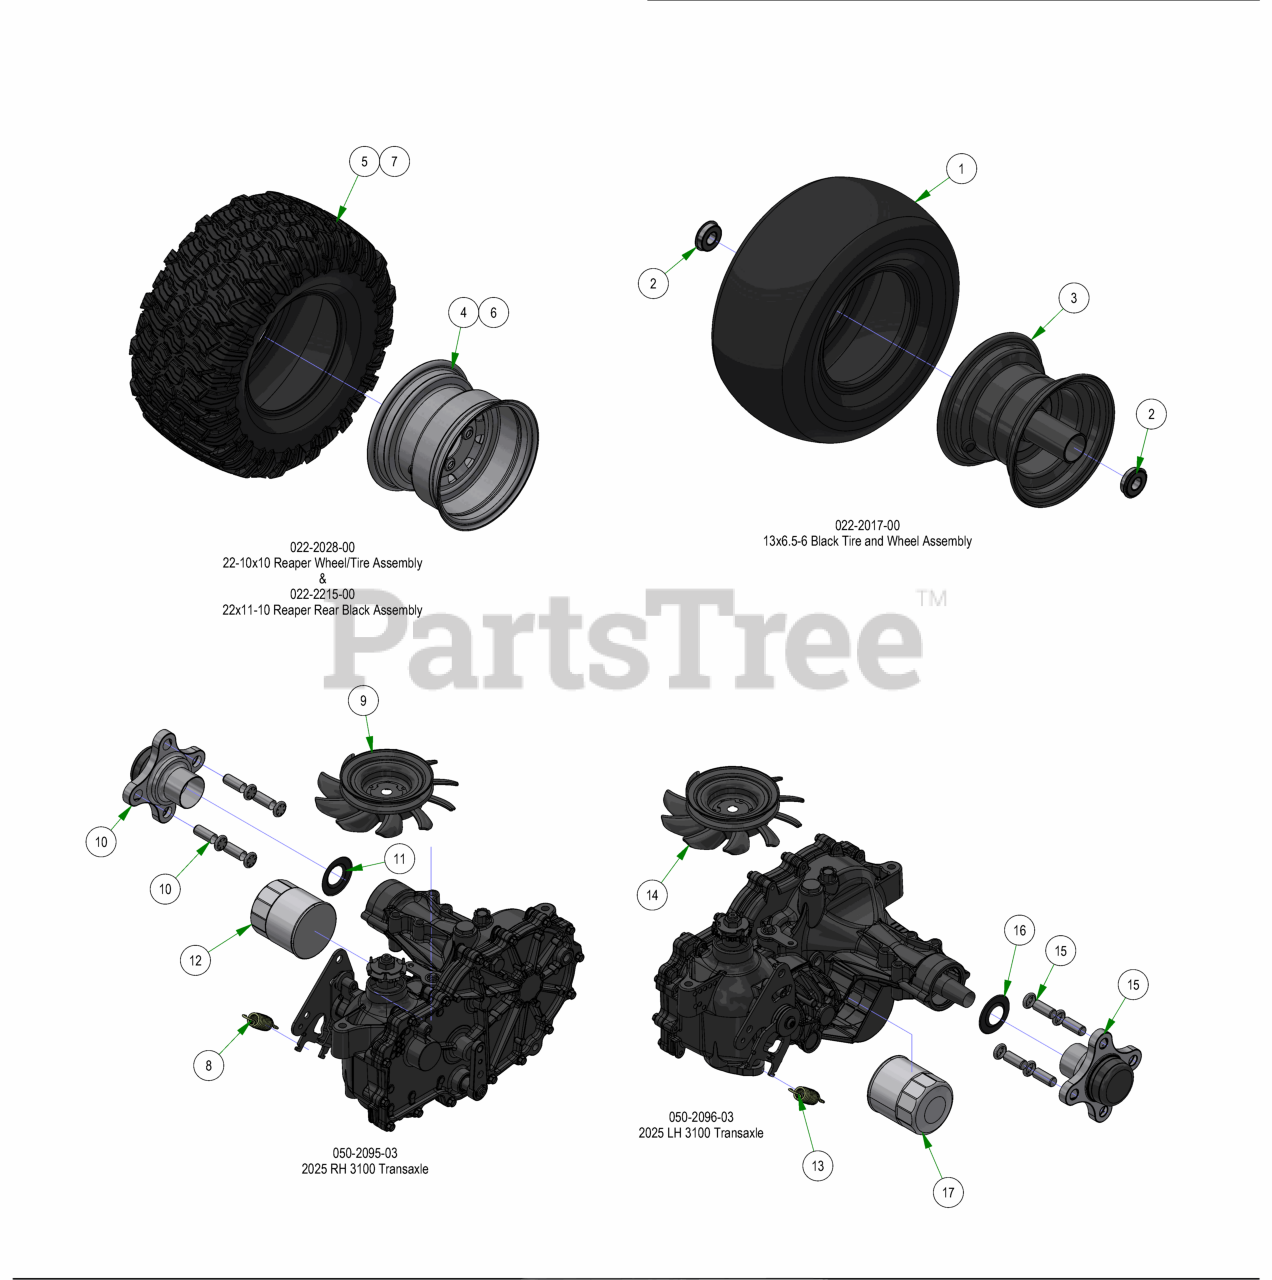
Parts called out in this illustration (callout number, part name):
1	13 x 6.50 - 6 Tire
2	Ball Bearing w/Retainer, 99502H-NR, .625 Bore x 1.375 OD x .4375 Width
3	Front Tire Rim
4	WHEEL, 10", BLACK
5	22-10x10 Reaper Tire Only
6	ZT Wheel Only 22x11-10
7	22x11-10 Reaper Rear TIRE ONLY
8	Transaxle Spring
9	2021 ZT/Maverick Transaxle Fan/Pulley Kit
10	ZT Transaxle Wheel Hub
11	2021 ZT/Maverick Transaxle Seat Kit (ZT-2800)
12	ZT Hydraulic Filter
13	Transaxle Spring
14	2021 ZT/Maverick Transaxle Fan/Pulley Kit
15	ZT Transaxle Wheel Hub
16	2021 ZT/Maverick Transaxle Seat Kit (ZT-2800)
17	ZT Hydraulic Filter
